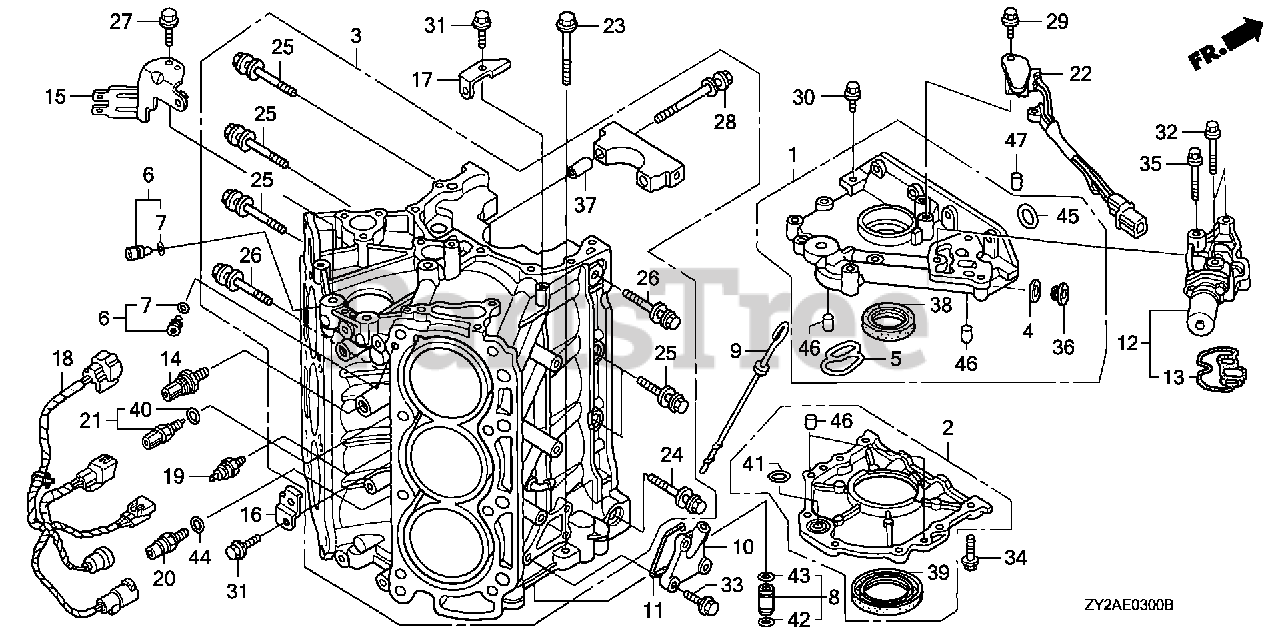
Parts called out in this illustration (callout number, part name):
1	COVER ASSY., CRANKCASE (UPPER) *NH8* (DARK GRAY)
2	CASE ASSY., OIL SEAL
3	BLOCK ASSY., CYLINDER *NH8* (DARK GRAY)
4	WASHER, SEALING (22MM)
5	GASKET, OIL HOLE
6	ORIFICE ASSY., OIL CONTROL
7	O-RING (8.8X2.4)
8	JOINT ASSY., OIL PIPE
9	DIPSTICK, OIL
10	COVER, OIL LEVEL GAUGE *NH8* (DARK GRAY)
10	COVER, OIL LEVEL GAUGE
11	GASKET, OIL LEVEL GAUGE
12	VALVE ASSY., SPOOL *NH8* (DARK GRAY)
13	FILTER ASSY., SPOOL VALVE
14	SENSOR ASSY., KNOCK
15	BRACKET, CONNECTOR D
16	BRACKET, CLIP B
17	BRACKET B, HARNESS CLIP
18	WIRE, SWITCH
19	SWITCH ASSY., OIL PRESSURE
20	SWITCH ASSY., OIL PRESSURE
21	SENSOR ASSY., WATER TEMPERATURE
22	SENSOR ASSY., CRANK
23	BOLT, FLANGE (12X95)
24	BOLT-WASHER (10X109)
25	BOLT-WASHER (10X60)
26	BOLT-WASHER (10X80)
27	BOLT, FLANGE (6X14) (CT200)
28	BOLT-WASHER (11X105)
29	BOLT, FLANGE (6X16)
30	BOLT, FLANGE (6X35)
31	BOLT, FLANGE (6X14)
32	BOLT, FLANGE (8X50)
33	BOLT, FLANGE (6X18)
34	BOLT, FLANGE (6X22)
35	BOLT, FLANGE (8X75)
36	BOLT, SEALING (22MM)
37	PIN, DOWEL (13X37)
38	OIL SEAL (41X66X8)
39	OIL SEAL (80X98X10) (NOK)
40	O-RING (9.5X1.9)
41	O-RING (26.2X2.4) (YAMADA SOMBOON)
42	O-RING (18.3X3.5)
43	O-RING (16.3X3.5)
44	O-RING (13X1.5) (ARAI)
45	O-RING (25X2.4) (NOK)
46	PIN, DOWEL (6X10)
47	PIN, DOWEL (5X8)
